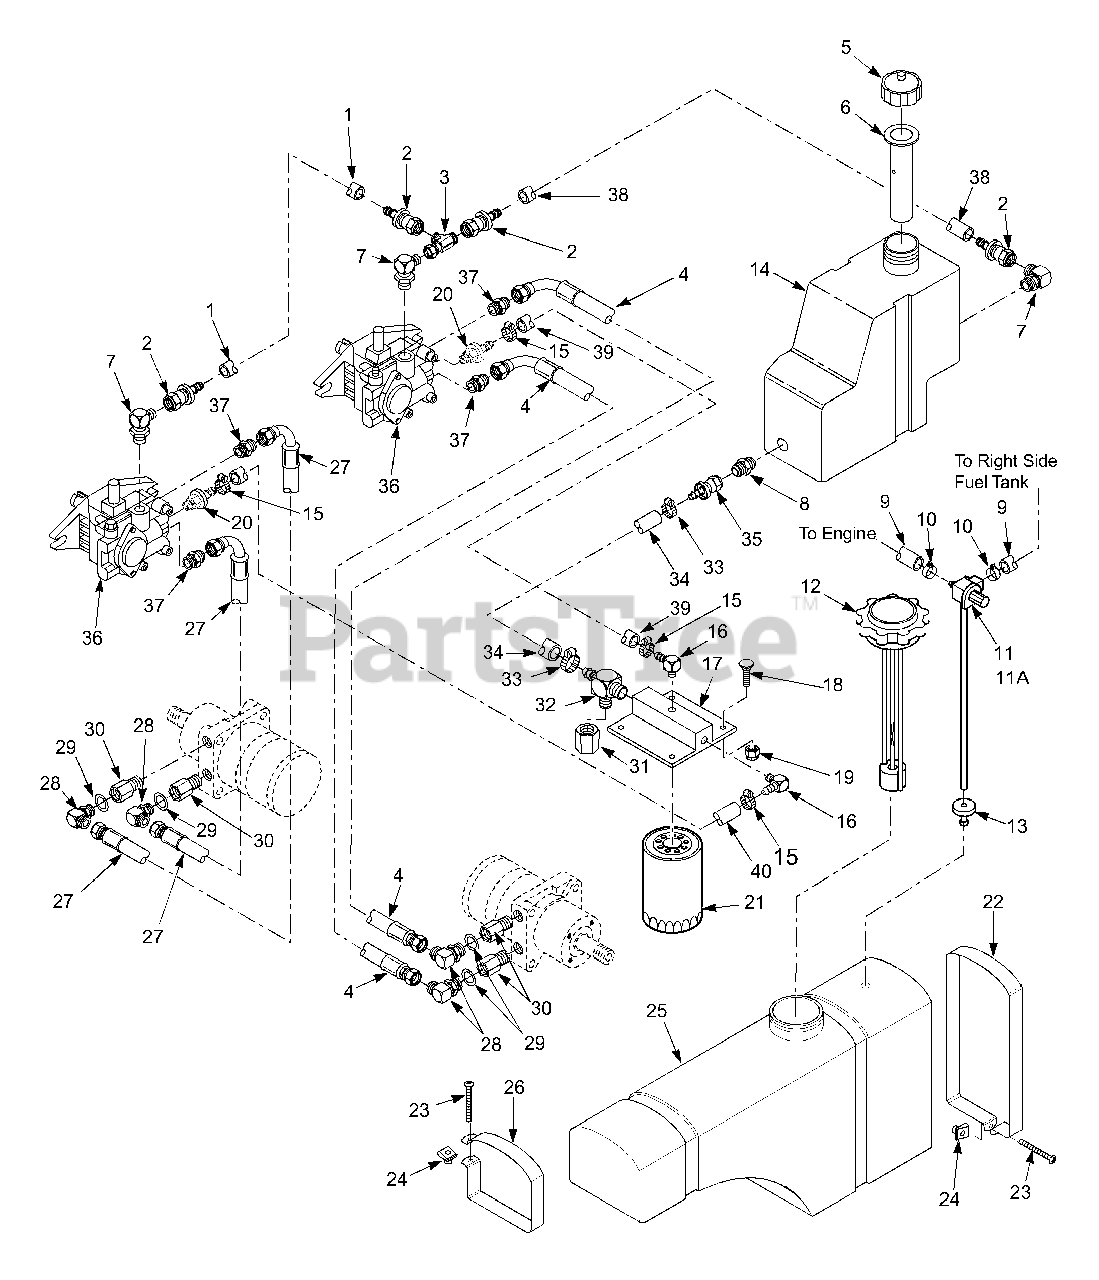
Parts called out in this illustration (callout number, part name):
1	Hose, 3/8 Pushlock 20" Long (order by the inch)
2	Coupling, 3/8 Hose x 9/16-18 Thread
3	Tee, Swivel 9/16-18 JIC
4	Hose Assembly, LH
5	Cap, Hydraulic Tank
6	Insert, Filler Neck
7	Elbow, 90 Degree 3/8 x 3/8
8	Tube, Union 1/2 x 1/2
9	Fuel Hose 1/4" ID
10	Clamp, Fuel Hose 1/4" Hose ID
11	Valve, Fuel Shutoff (LH Tank)
11A	Tube, Fuel Standoff (RH Tank)
12	Cap, Fuel Tank w/gauge
13	Bushing, Tank
14	Hydraulic Tank
16	Elbow, 1/4 NTP x 3/8 Hose Barb
17	Filter Head
18	Bolt, Hex Head 5/16-18 x 1"
19	Nut, Elastic Stop 5/16-18
20	Connector, 7/16 O-Ring x Hose Barb
21	Filter, Hydraulic
22	Strap, Fuel Tank Rear
23	Screw, 1/4-20 x 2"
24	U-Nut, 1/4-20
25	Fuel Tank
26	Strap, Fuel Tank Front
27	Hose Assembly, RH
28	Elbow, 90 Degree 1/2 x 1/2
29	O-Ring
30	O-Ring Bushing, 5/8 Tube
31	Cap, 3/4-16 JIC
32	Fitting, Tee Special
34	Hose, Return Line
35	Coupling, 1/2 Hose x 3/4-16 Thread
36	Pump, BDP 10L
37	Tube, Union 1/2 x 1/2
38	Hose, 3/8 Pushlock 5" Long (order by the inch)
39	Hose, 3/8 Pushlock 36" Long (order by the inch)
40	Hose, 3/8 Pushlock 30" Long (order by the inch)
